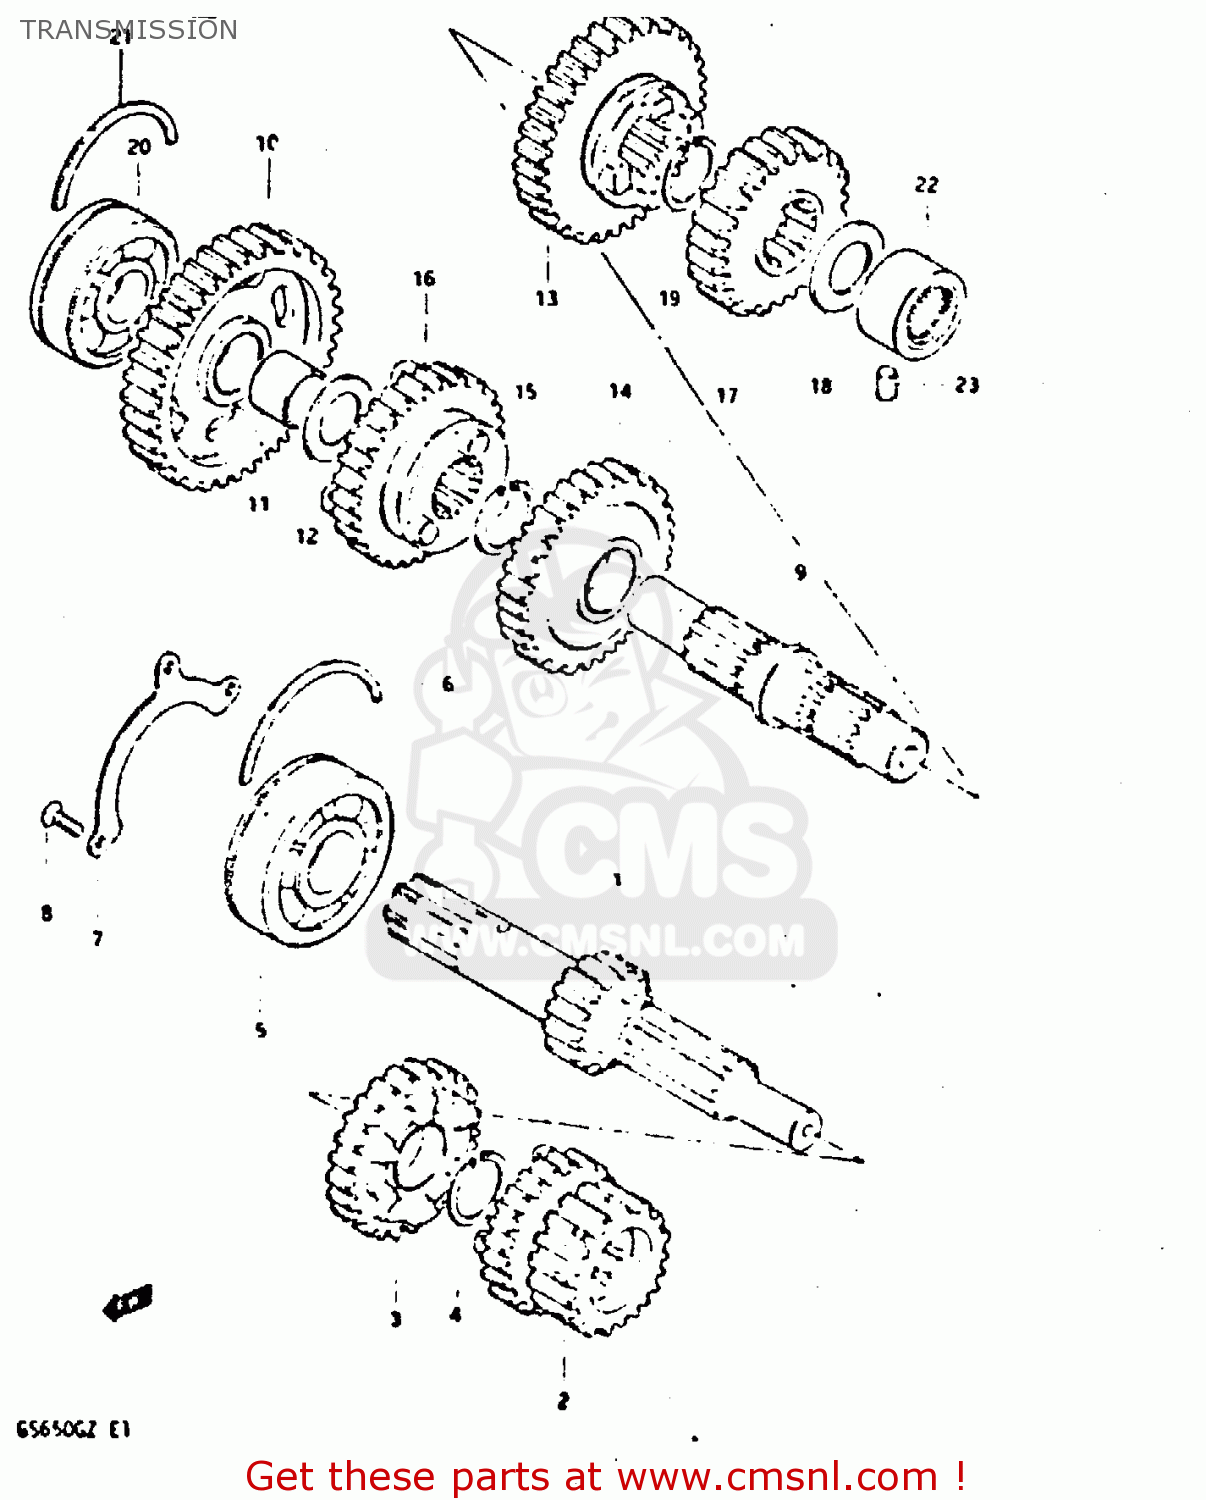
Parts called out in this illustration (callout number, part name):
1	SHAFT,COUNTER
2	GEAR,SECOND DRIVE
3	GEAR,FOURTH DRIVE
4	CIRCLIP
5	BEARING(25X62X17)
6	C-RING
7	RETAINER,CNTR SHAFT BEARING
8	SCREW
9	SHAFT,DRIVE
10	GEAR,FIRST DRIVEN
11	BUSHING
12	WASHER
13	GEAR,SECOND DRIVEN
14	GEAR,THIRD DRIVEN
15	CIRCLIP
16	GEAR,FOURTH DRIVEN
17	GEAR,REDUCTION(NT:24)
18	THRUST WASHER,REDUCTION
19	CIRCLIP
20	BALL BEARING 20X47X14
21	C RING
22	BEARING(20X34X16)
23	PIN
